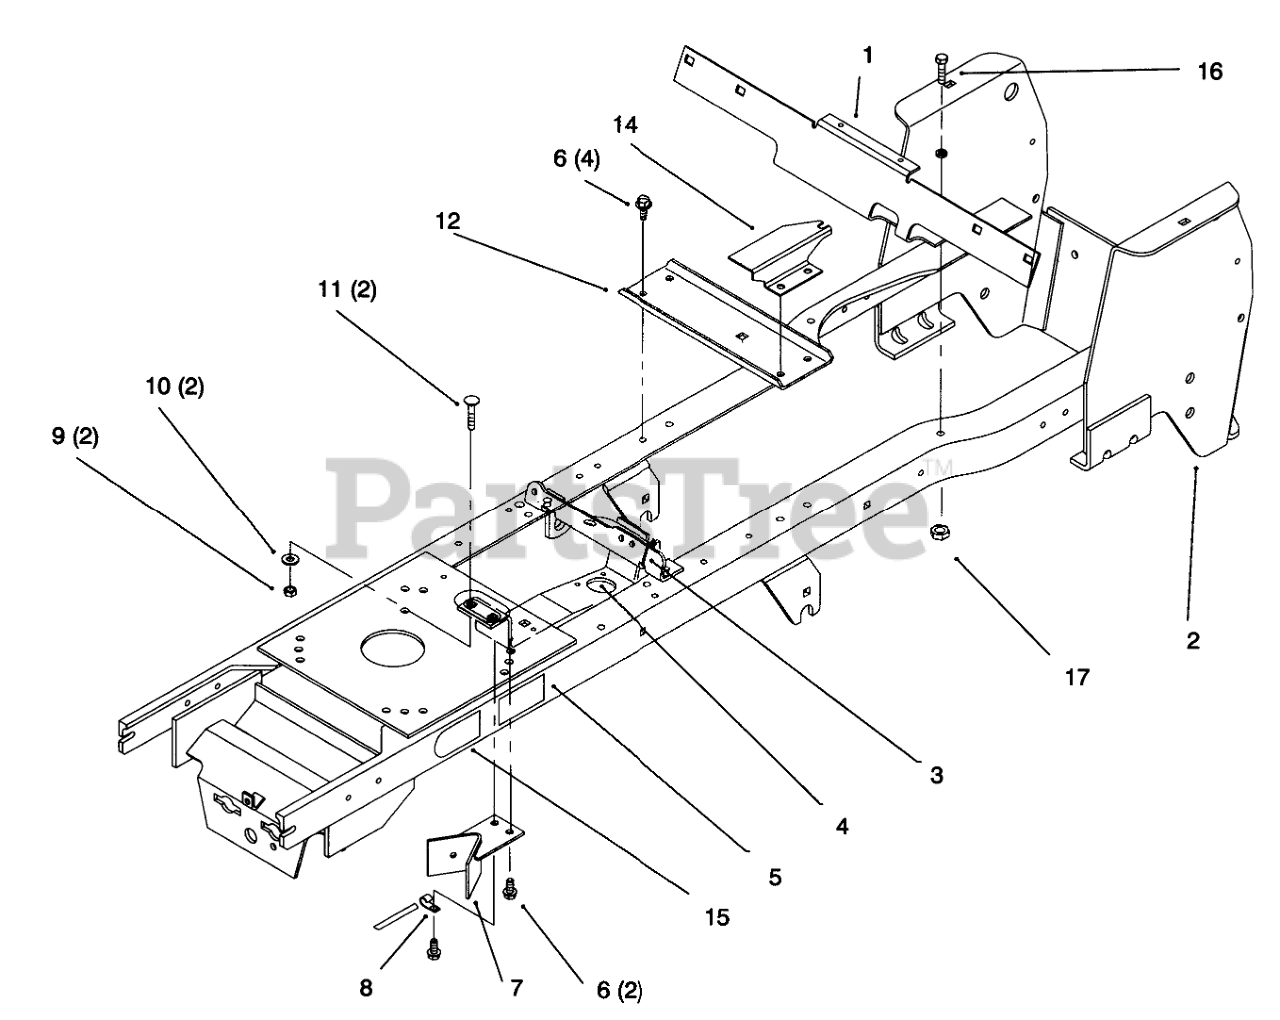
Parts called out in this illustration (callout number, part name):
1	SUPPORT - FENDER
2	Frame W.a.
3	TIE-CABLE
4	STEERING BRKT WA
5	Decal-Belt Install (Only On: 72042, 72043)
5	Decal-Belt Install (Only On: 72062, 72063, 72103)
6	SCREW-HWHTF
7	WLDMT-PTO STOP
8	CLIP
9	NUT-LOCK, NI
10	WASHER-PLAIN
11	BOLT-CARR
12	BRACKET-IDLER PLATE
14	BRACKET-HOC GAGE
15	Screw-HH (Only On: 72043, 72063, 72103)
15	DECAL-ATTACH A-MATIC
16	Screw-HH (Only On: 72043, 72063, 72103)
17	Nut-Lock (Only On: 72043, 72063, 72103)
